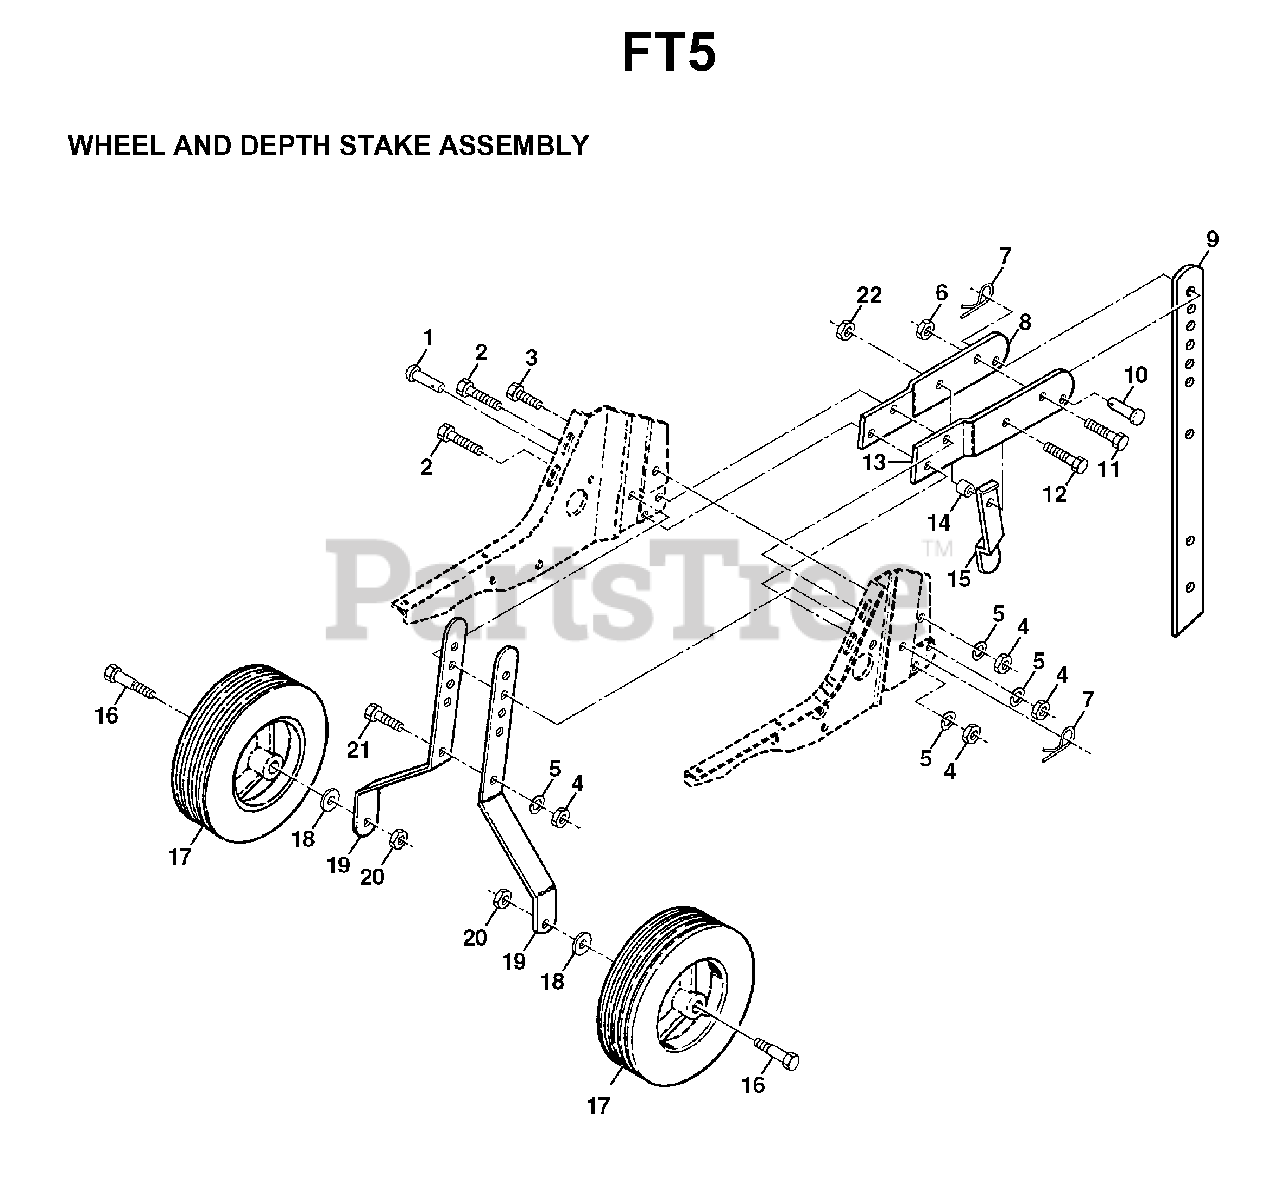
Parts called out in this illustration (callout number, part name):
1	PIN
2	BOLT
3	BOLT
5	LOCKWASHER
6	NUT
7	SPRING.RETAINER
8	SUPPORT.STAKE.RH.BLACK
9	RP STAKE.DEPTH.13.25.W/9HOLES
11	BOLT
12	BOLT
16	BOLT.SHOULDER
18	WASHER
20	LOCKNUT
21	BOLT RB
22	NUT.71038.31-18.HEX.NYLOCK
